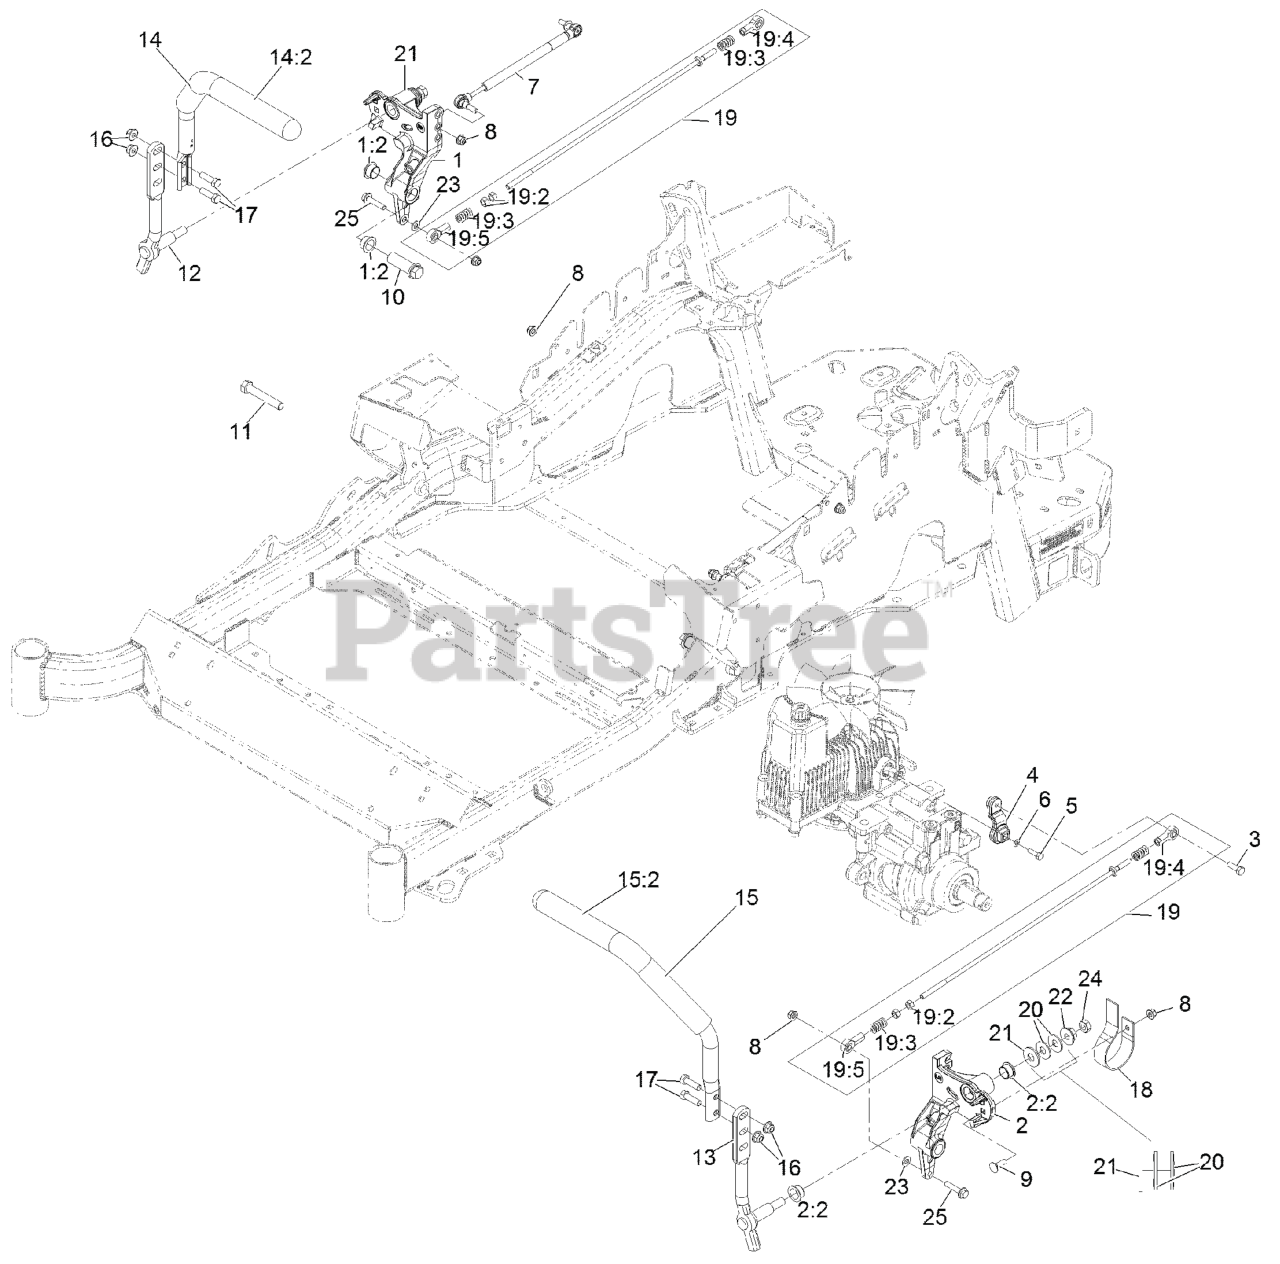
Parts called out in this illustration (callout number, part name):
1	RH MOTION CONTROL AND BUSHING ASM
1:2	BUSHING-FLANGE
2	LH MOTION CONTROL AND BUSHING ASM
2:2	BUSHING-FLANGE
3	SCREW-HH, THREAD LOCKING
4	ARM-CONTROL, PUMP
5	SCREW-HH
6	WASHER-SPRING
7	DAMPER-CONTROL, MOTION
8	NUT-HF, NI
9	BOLT-CARR
10	HUB-THREADED
11	SCREW-HH
12	LEVER-CONTROL MOTION, RH
13	LEVER-CONTROL MOTION, LH
14	RH HANDLE ASM
14:2	GRIP-LEVER, CONTROL
15	LH HANDLE ASM
15:2	GRIP-LEVER, CONTROL
16	NUT-HF, NI
17	SCREW-HH
18	SPRING-LEAF
19	PUMP LINKAGE REAR ASM
19:2	NUT-HEX
19:3	SPRING-COMPRESSION
19:4	BALLJOINT-LH
19:5	BALLJOINT-RH
20	WASHER-SPRING
21	WASHER-FLAT
23	WASHER-PLAIN
24	NUT-JAM
25	SCREW-HHF
